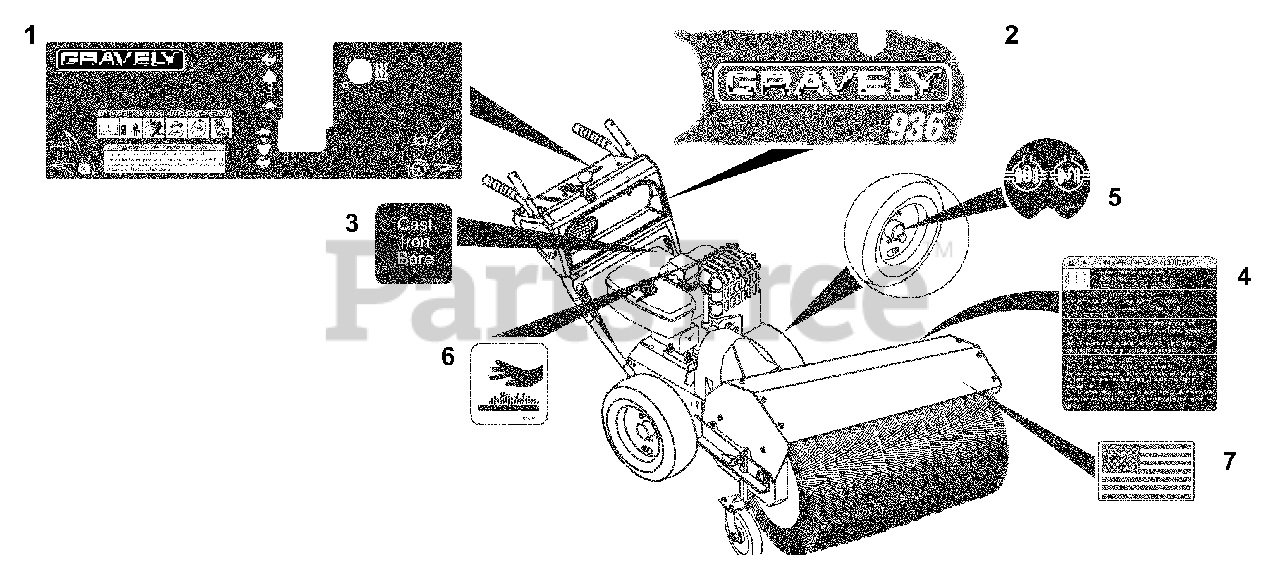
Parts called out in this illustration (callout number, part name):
1	Decal, 936 Control Panel
2	Decal, 936 Dash
3	Decal, Cast Iron Bore
4	Decal, Caution
5	Decal, Differential Lock
6	Decal, Hot Surface
7	Decal, American Flag
